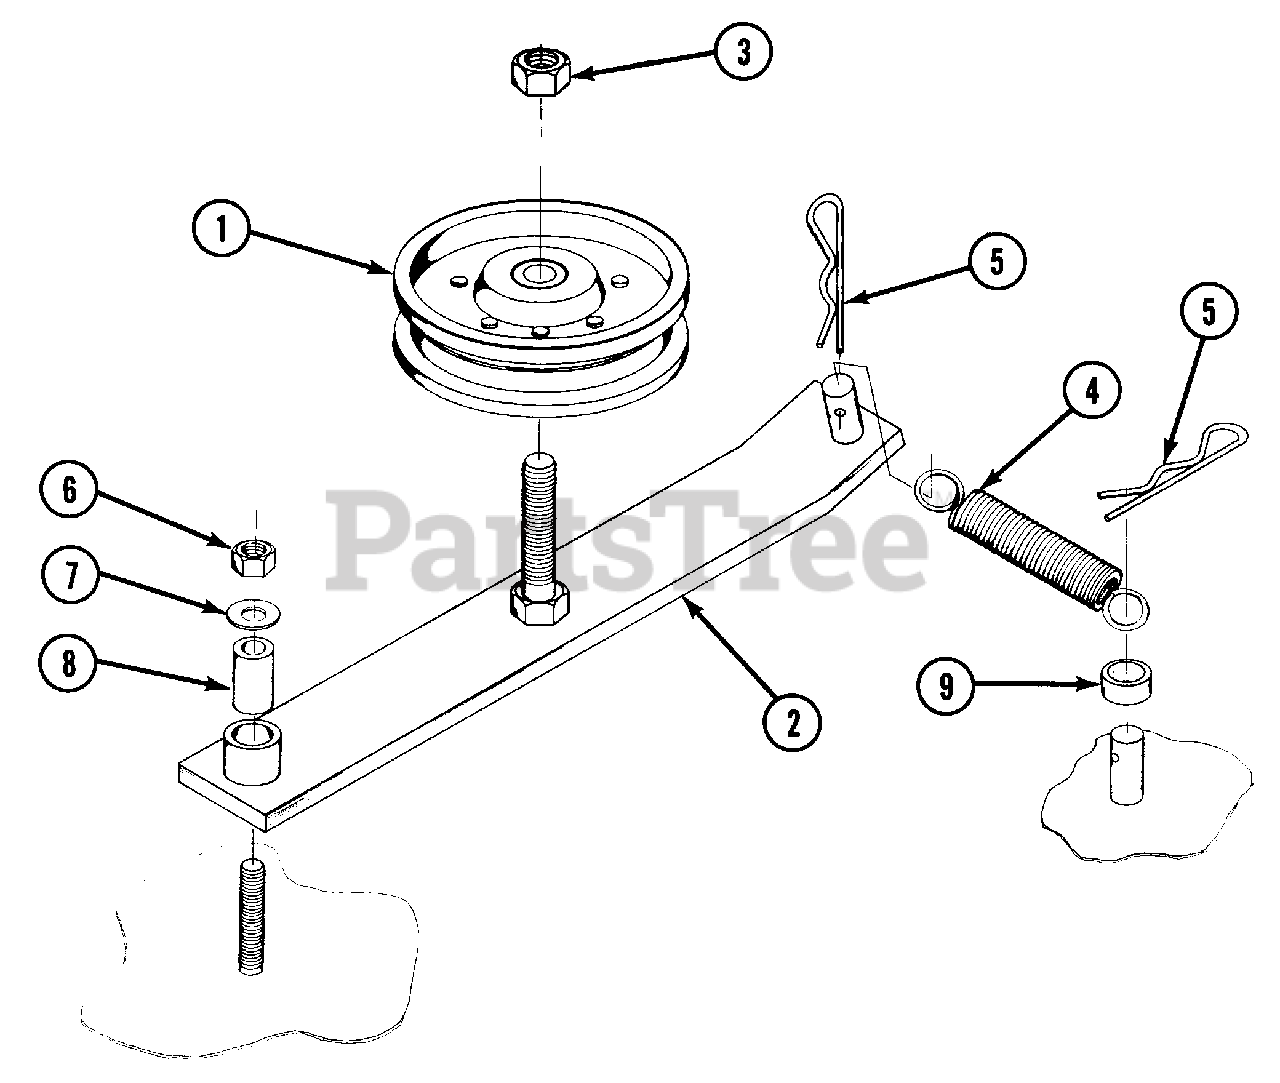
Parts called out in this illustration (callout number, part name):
1	PULLEY, FLAT IDLERS 1/2 BORE 4", OD
2	SINGLE IDLER WELDMENT
3	LOCKNUT, HEX, 1/2-13, W/NYLOC
4	SPRINGER EXTENSIONS 3/4 X 4" OAL
5	PIN, HAIR SPRINGER 1/8 X 2-1/2
6	LOCKNUT, HEX, 3/8-16 W/NYLOC
7	WASHER, 3/8 STD, FLAT, W SERIES
8	BEARINGS OILITE, 3/8 ID X 5/8 0D
9	SPRING SPACER
